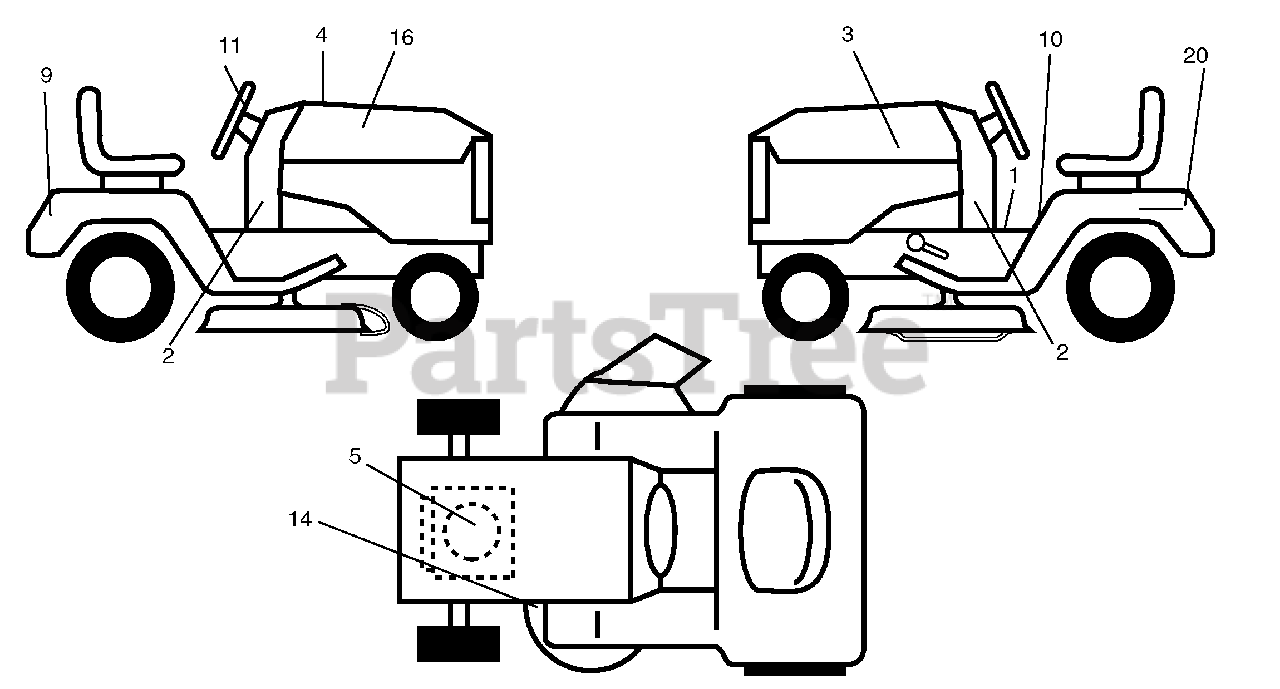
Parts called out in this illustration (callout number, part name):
1	Decal Oper
2	Decal LWRDASH
3	Decal Hood LH
4	Decal Replace
5	Decal HP Engine
9	Decal Fender Logo
10	Decal Fender Danger E/S
11	Decal Ins Strg Whl
14	Decal V-Belt Schematic
16	Decal Hood Rh
20	Decal Bat Dan/Psn
20	Decal Handle Lft Height Adjust
20	Manual Operator's E&S
20	Manual Parts
